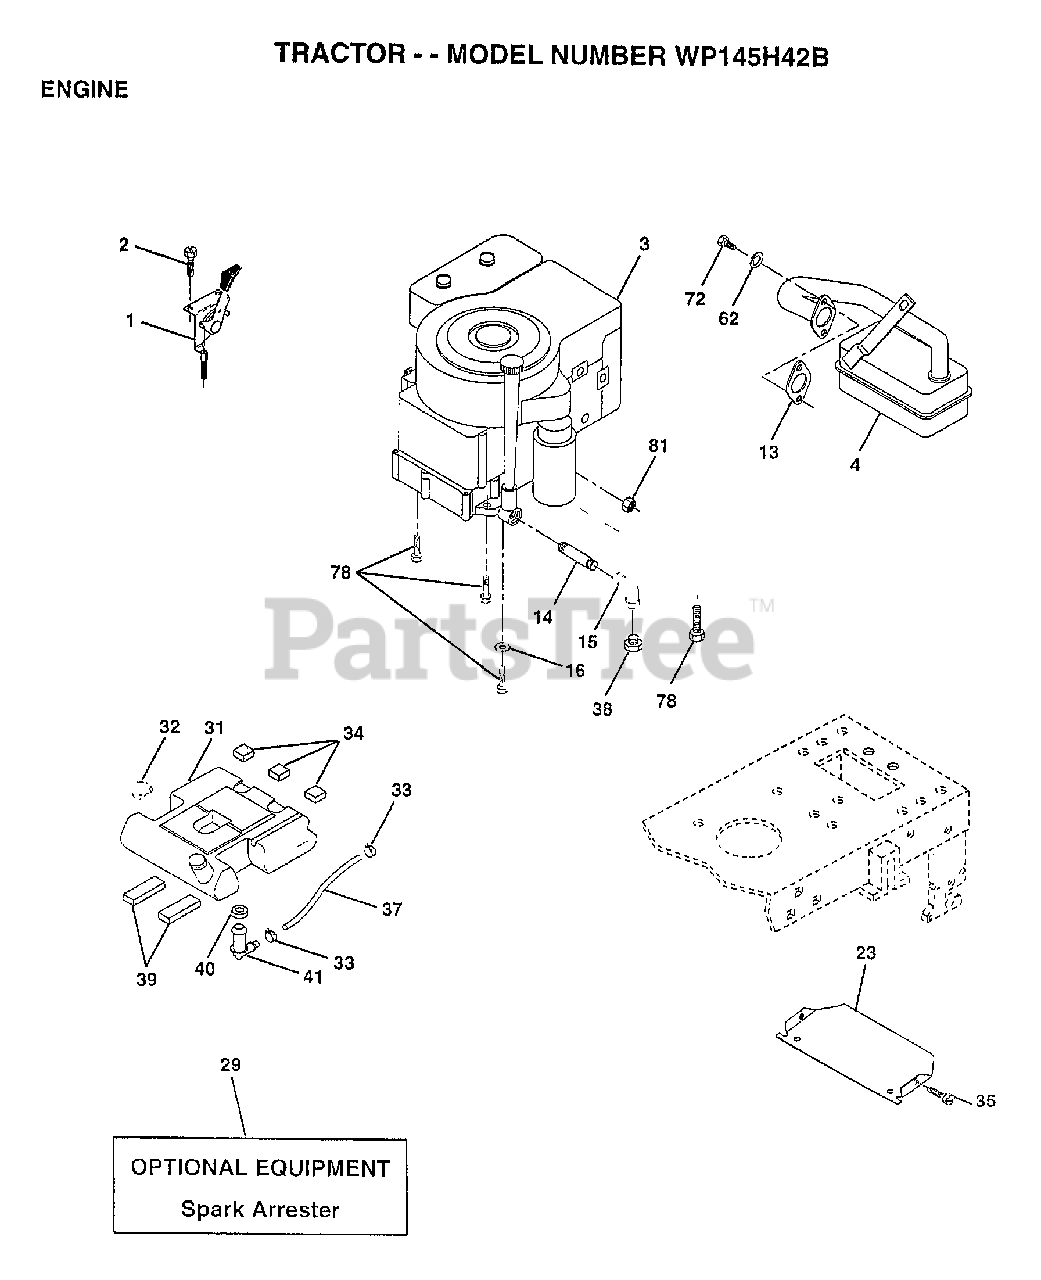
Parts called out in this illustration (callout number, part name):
1	"CONTROL,THROTTLE"
2	SCREW LT
4	MUFFLER
13	GASKET ENG 1 313 LD TIN PLATED
14	PIPE NIPPLE
15	ELBOW
16	LOCKWASHER
23	SHIELD-HEAT
31	TANK FUEL REAR
32	CAP ASM FUEL
33	HOSE CLAMP
34	PAD-SPACER LT
35	SCREW
37	FUEL LINE T
39	PAD IDLER TI
40	BUSHING OUTLET T
41	STEM.TANK.FUEL
62	LOCKWASHER
72	SCREW
78	SCREW
81	NUT
